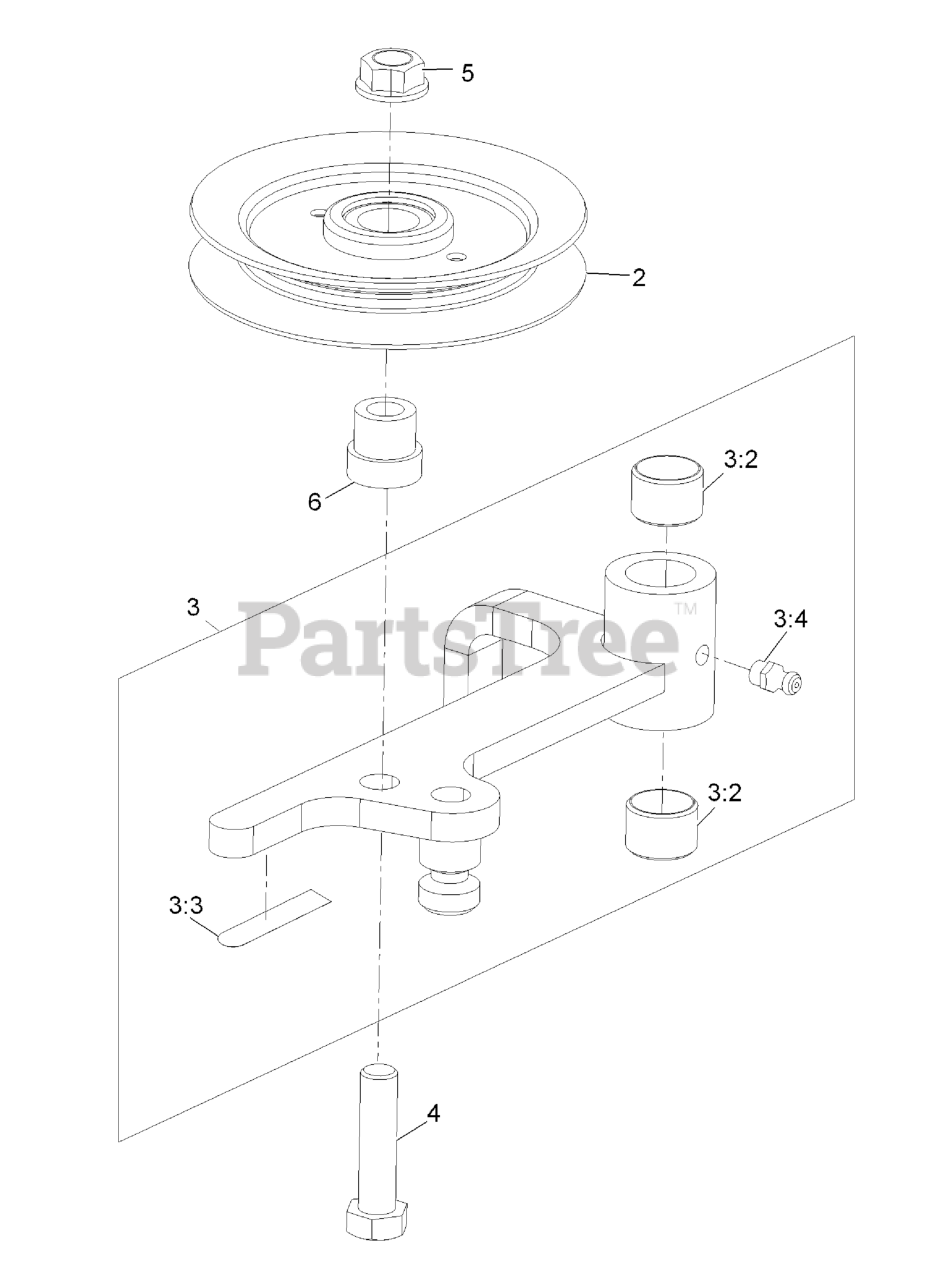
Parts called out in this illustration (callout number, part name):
3	ASM, IDLER ARM - SERVICE
3:2	BUSHING
3:3	DECAL-WARNING
3:4	FITTING-GREASE
4	SCREW-HH
5	NUT-HHF, WHIZ
6	HUB,SPACER
